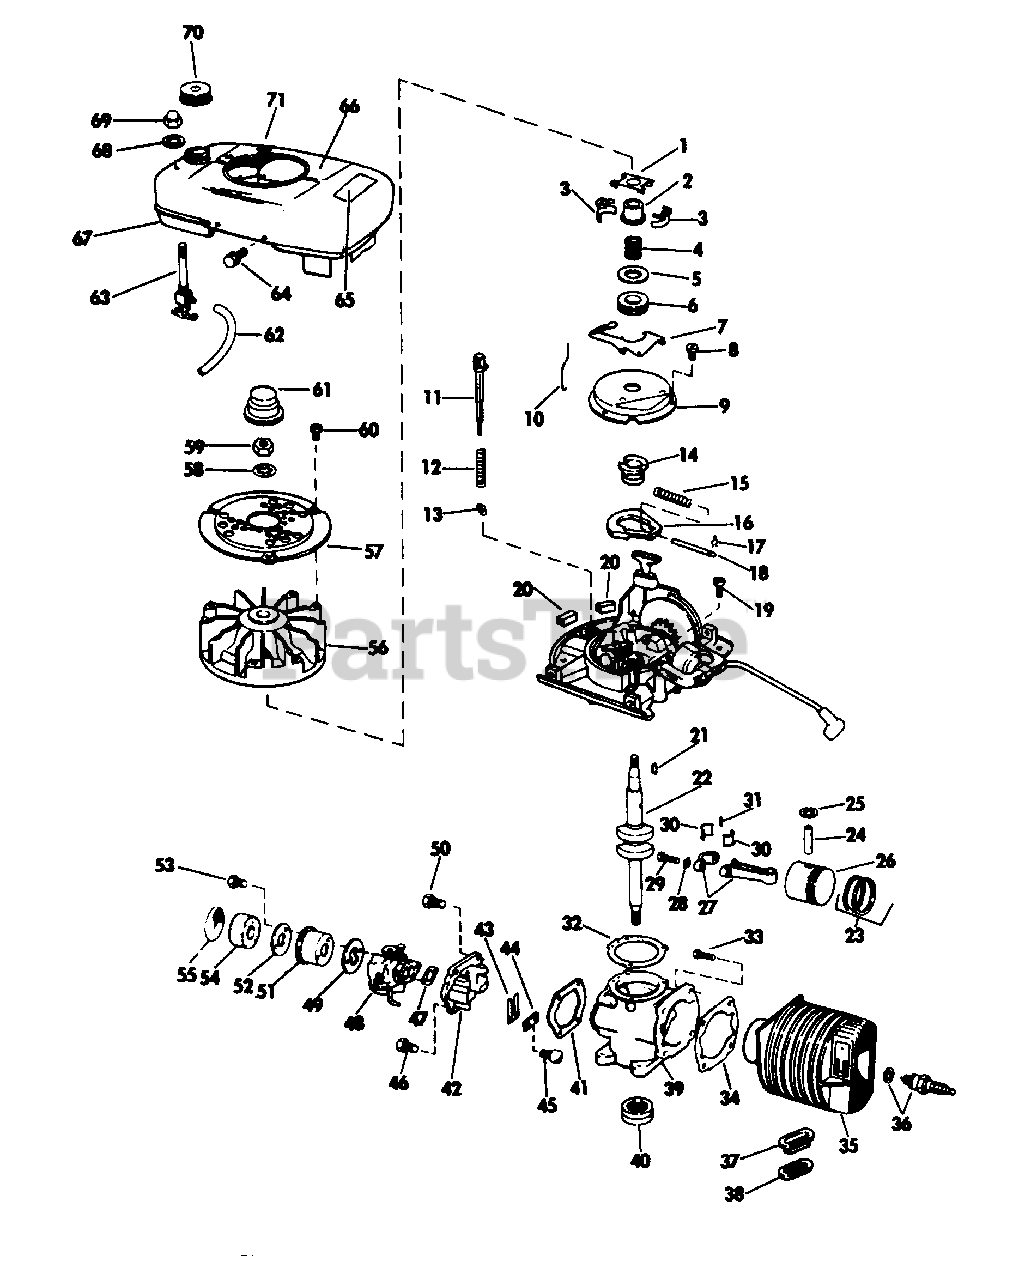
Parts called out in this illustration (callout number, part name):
1	Yoke-Governor
2	Collar-Governor
3	Weight-Governor
4	Spring-Governor
5	Thrust Washer
6	Collar-Thrust
7	Lever-Governor
8	Screw-Attaching Dust Cover
9	Dust Cover
10	Rod-Governor
11	Bar-Shut-Off and Primer
12	Spring-Shut-Off Switch
13	Blade-Switch
14	Cam-Spark Advance
15	Spring-Spark Advance
16	Flyweight-Spark Advance
17	Retainer-Spring
18	Pin-Spark Advance
19	Screw-Arm. Plate to Crankcase
20	Pad-Rubber, Arm. Plate
21	Key-Crankshaft
22	Crankshaft
23	Ring Set (2 Rings)
24	Wrist Pin
25	Retaining Ring-Wrist Pin
27	Connecting Rod Assy.
28	Lockplate
30	Liners-Connecting Rod
31	Needle Bearing Set
32	Gasket-Crkc. to Arm. Pl. .005 in.
32	Gasket-Crkc. to Arm. Pl. .010 in.
33	Screw-Machine, Cyl. to Crkc.
34	Gasket-Cyl. to Crankcase
35	Cylinder and Sleeve Assy.
36	Spark Plug and Gasket
37	Sleeve-Exhaust Gasket
38	Gasket-Exhaust
39	Crankcase and Seal Assy.
40	Oil Seal
41	Gasket-Reed Plate
42	Reed Plate Assembly
44	Plate-Back-Up
45	Screw-Machine
46	Scr.-Reed Pl. to Crkc.
47	Gasket-Carburetor
48	Carburetor Assembly
50	Scr.-Reed Pl. to Crkc.
51	Cup-Air Filter
52	Plate-Back-Up
53	Screw-Filter to Carburetor
54	Element-Air Filter
55	Screen-Air Filter
56	Flywheel Assy.
57	Screen Flywheel
58	Lockwasher-Flywheel
59	Nut-Flywheel
60	Screw-Thd. Cutting
61	Cap-Flywheel
62	Gas Line
63	Shut-Off Valve
64	Screw-Shroud to Armature Plate
65	Decal-Instruction
66	Decal-LAWN-BOY
67	Gas Tank Assy.
68	Lockwasher
70	Cap
71	Shroud and Shield Assy.
